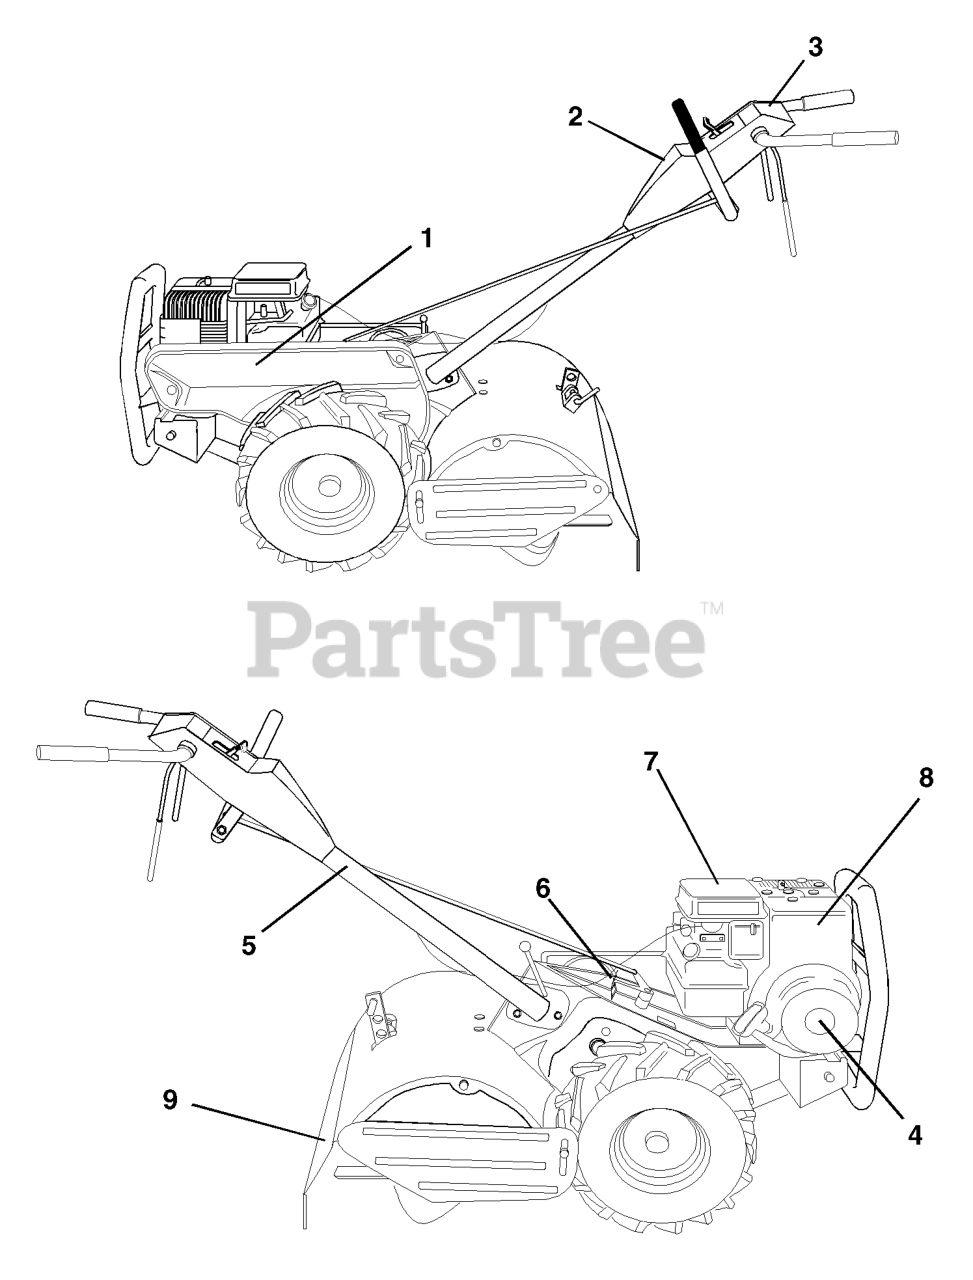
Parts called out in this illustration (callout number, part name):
1	DECAL, LOGO
2	DECAL, LOGO
3	DECAL, LOGO
4	Decal, 5.5 HP
5	DECAL TI (2 2)
6	Decal, Shift Indicator
8	DECAL, B & S ENGINE
9	DECAL TI
